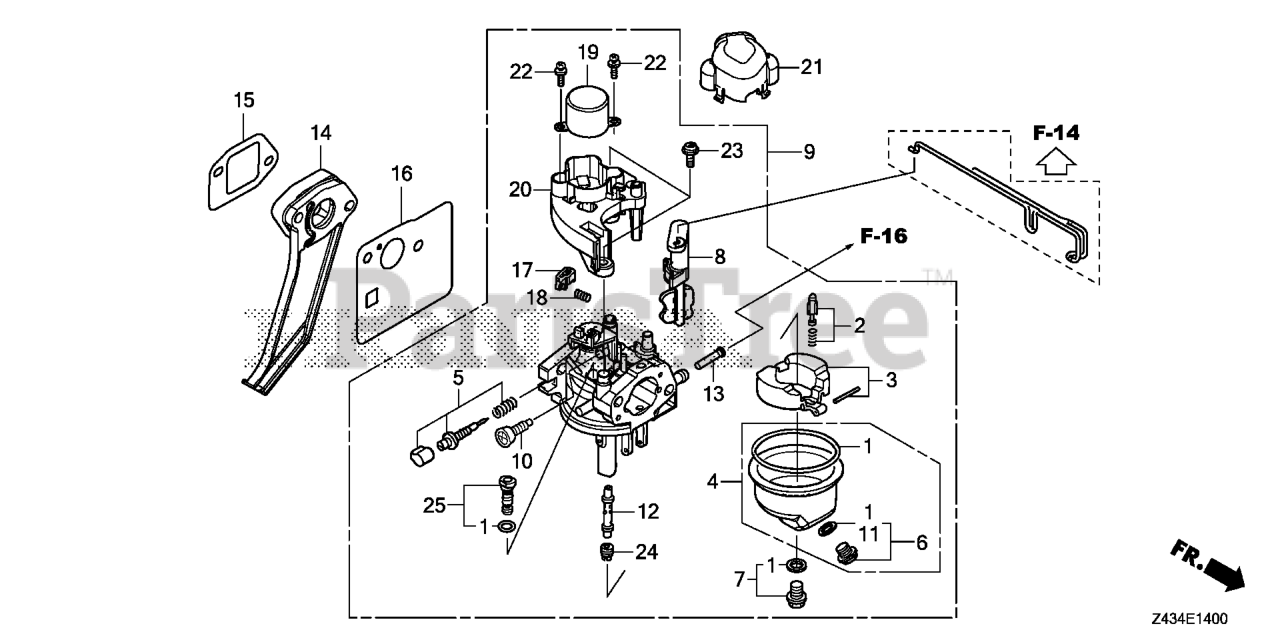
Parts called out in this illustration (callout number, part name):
1	GASKET SET (CARBURETOR NO.)
2	VALVE SET, FLOAT (CARBURETOR NO.) (SEAT NOT INCLUDED)
3	FLOAT SET
4	CHAMBER SET, FLOAT
5	SCREW SET (Honda Code 4219879). (CARBURETOR NO.)
6	SCREW SET, DRAIN
7	SCREW SET (CARBURETOR NO.)
9	CARBURETOR ASSY. (BEA1L A)
10	SCREW, THROTTLE STOP
11	WASHER, PLAIN (6.2X10.7 DRAIN) (CARBURETOR NO.)
12	NOZZLE, MAIN
13	SCREEN, FUEL STRAINER
14	INSULATOR, CARBURETOR
15	GASKET, INSULATOR
16	GASKET, CARBURETOR
17	LEVER, LINK (CARBURETOR NO.)
18	SPRING, COMPRESSION COIL (CARBURETOR NO.)
19	MOTOR, THROTTLE CONTROL
20	BRACKET, THROTTLE MOTOR
21	COVER, THROTTLE MOTOR
22	SCREW-WASHER (3X8)
23	SCREW-WASHER (4X10)
24	JET, MAIN (#72) (CARBURETOR NO.)
24	JET, MAIN (#75) (CARBURETOR NO.)
24	JET, MAIN (#70)
25	JET SET, PILOT (#35)
